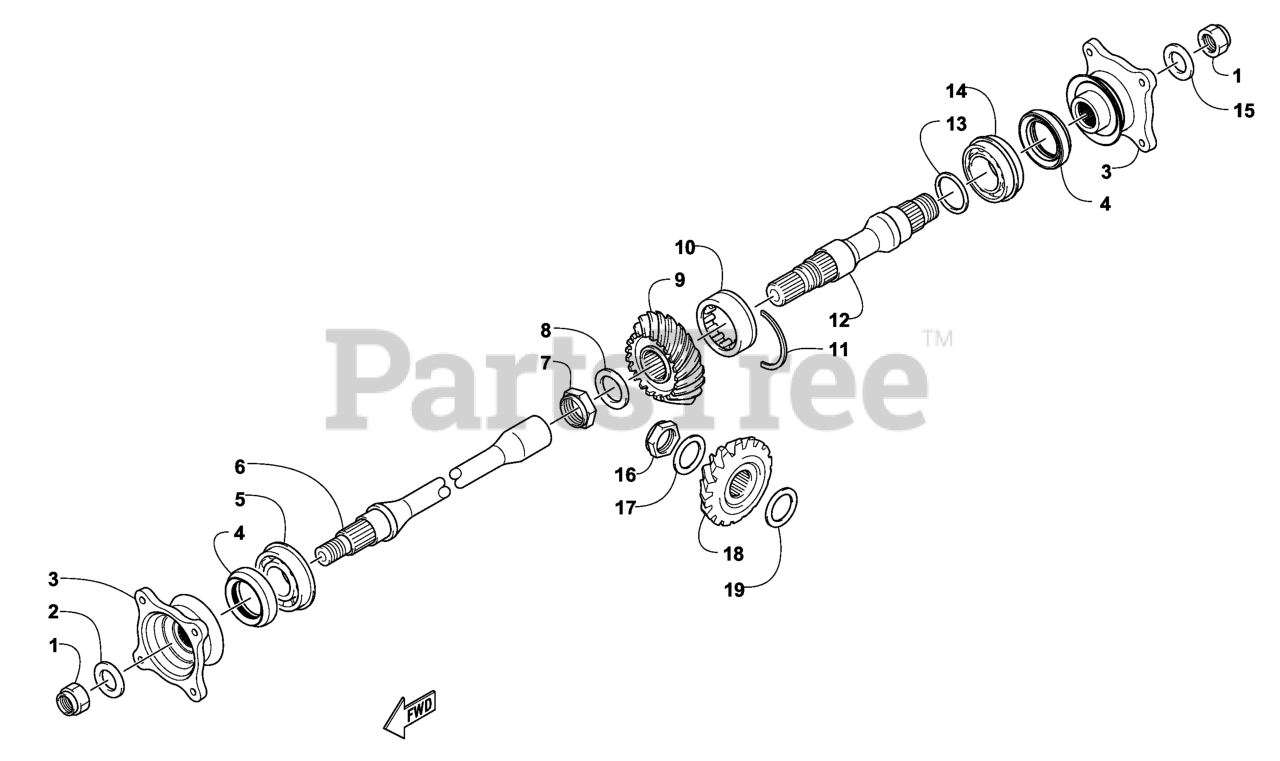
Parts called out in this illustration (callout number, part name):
3	FLANGE-OUTPUT JOINT, REAR
4	SEAL-OIL, REAR SECONDARY
5	BEARING
6	SHAFT-SECONDARY, DRIVEN (
9	GEAR-DRIVEN, SECONDARY
10	BEARING-NEEDLE, ROLLER (W
11	C-RING-DRIVEN BEARING
12	SHAFT-SECONDARY DRIVEN, R
13	SHIM (A DRIVEN BEVEL GEAR
13	SHIM (B DRIVEN BEVEL GEAR
13	SHIM (C DRIVEN BEVEL GEAR
13	SHIM (D DRIVEN BEVEL GEAR
13	SHIM (DRIVEN BEVEL GEAR)
14	BEARING-CONRAD,WITH SNAPR
16	NUT-HH, COLLARD
17	WASHER-THRUST
18	GEAR-DRIVEN, SECONDARY
19	SHIM (DRIVEN BEVEL GEAR)
